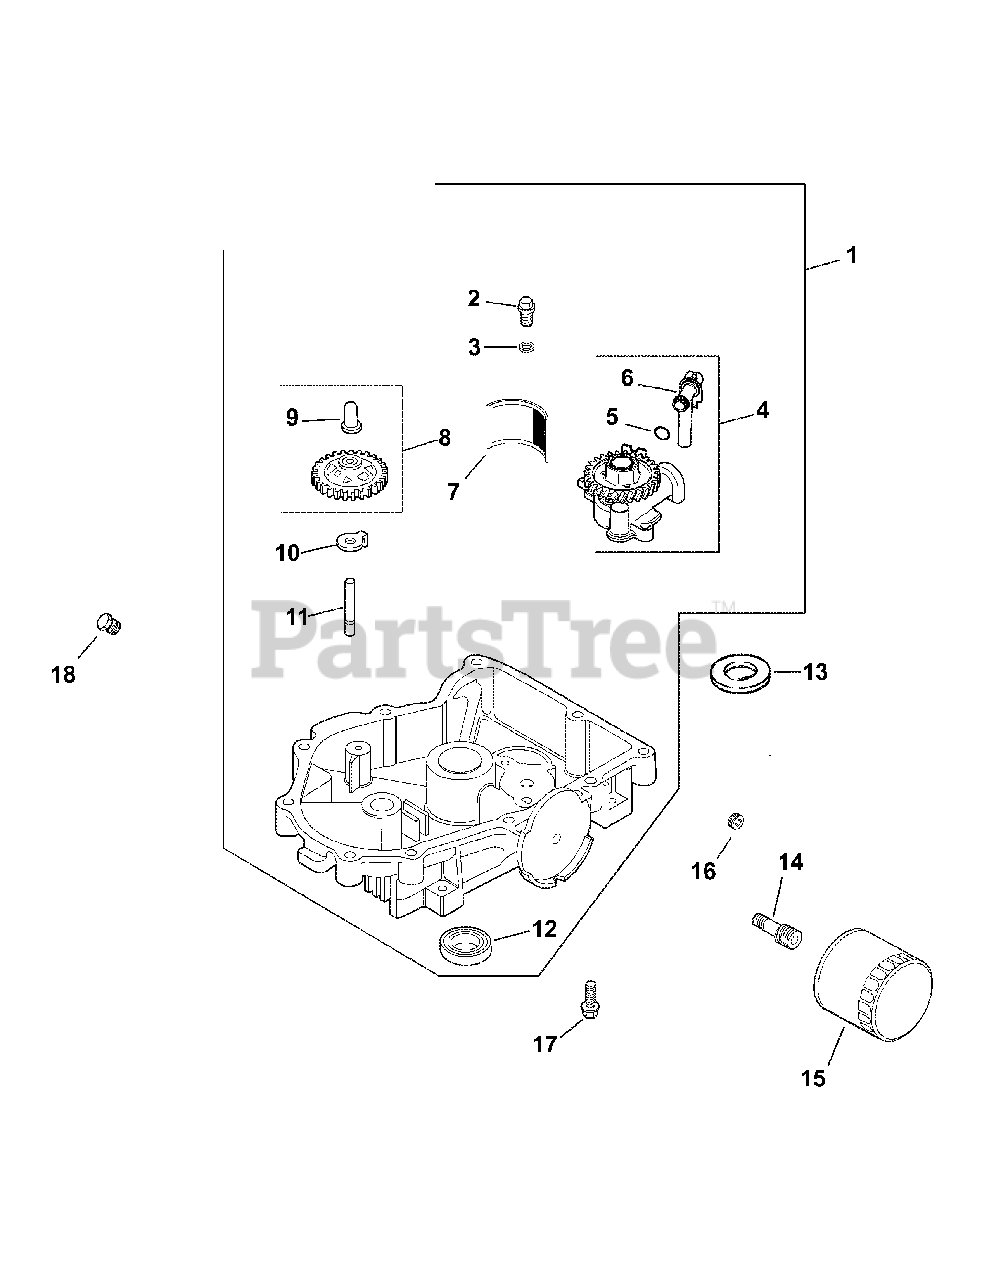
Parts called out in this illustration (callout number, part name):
1	Pan, Oil Assembly
2	Screw, SHD THD FRM M6 x 1.0 x 25
3	Washer, Flat 6MM
4	Kit, Oil Pump Assembly
5	O-Ring, Oil Pick-Up
6	Tube, Oil Pick Up
8	Kit, Governor Gear w/ Pin
9	Pin, Governor Regulating
11	Shaft, Governor Gear
14	Nipple, Oil Filter
16	Plug, Pipe CTSK 3/8"
17	Screw, Flg M8 x 1.25 x 45
18	Plug, Hd Pipe 3/8"
